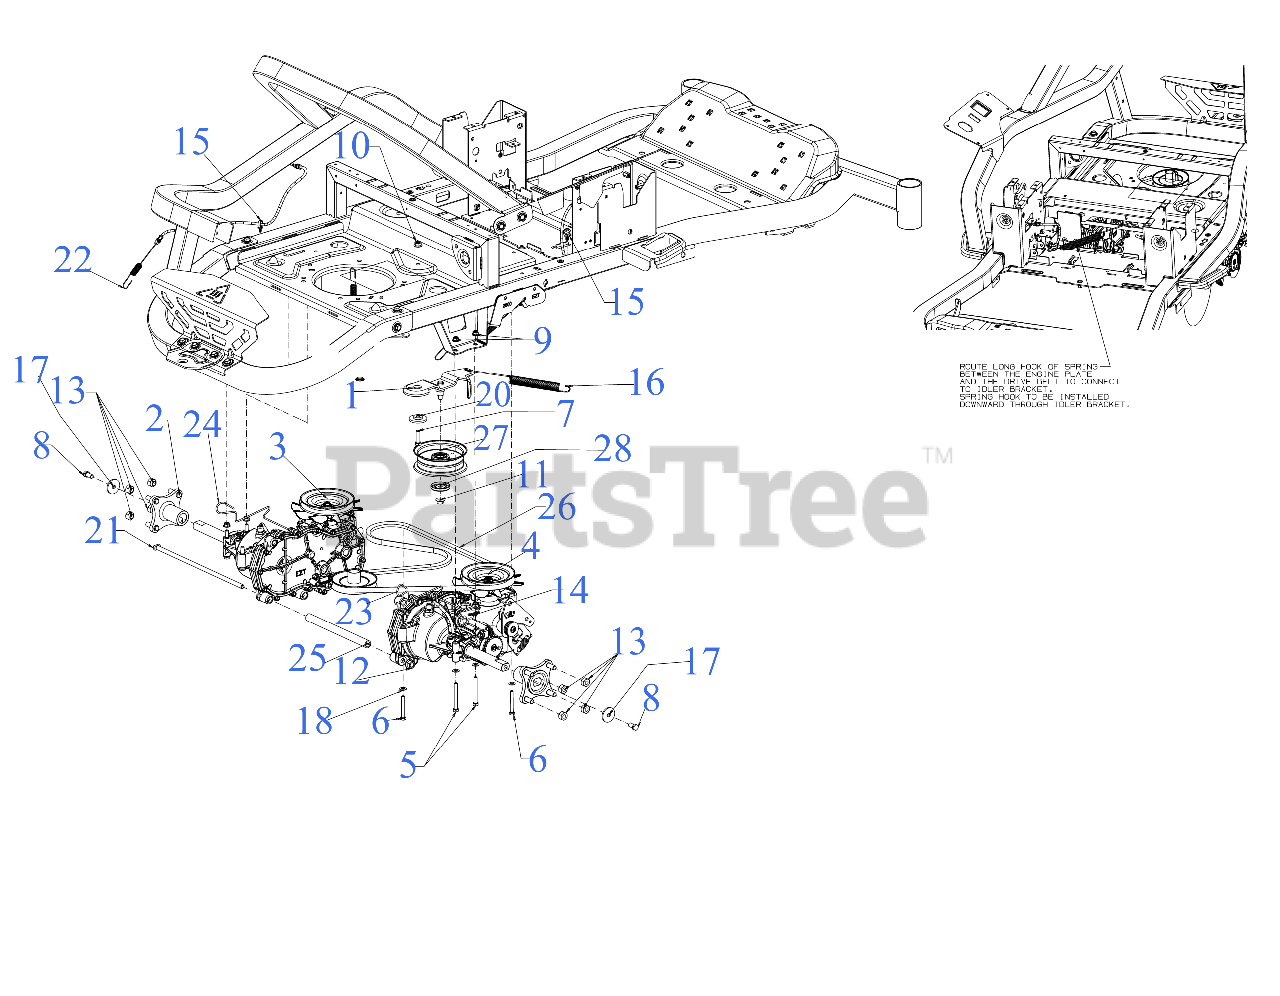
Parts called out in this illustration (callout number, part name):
1	DRIVE IDLER BRACKET ASSEMBLY
2	WHEEL HUB ASSEMBLY
2	STUD 7/16-14 x 1.6
3	HYDRO TRANSMISSION (LH)
4	HYDRO TRANSMISSION (RH)
5	HEX SCREW 5/16-18 x 2.75
6	HEX SCREW 5/16-18 x 2.25 GR5
7	SCREW 3/8-16 x 1.25 GR5
8	SCREW 3/8-16 x .75 GR 5
9	FLANGE LOCK NUT 5/16-18
11	FLANGE LOCK NUT
12	FLANGE LOCK NUT
13	LUG NUT 7/16-14
14	BOW TIE COTTER PIN 1/4-5/16
15	CABLE RETAINER CLIP
16	EXTENSION SPRING .75 DIA X 10.27
17	FLAT WASHER
18	FLAT WASHER
20	SHOULDER SPACER
21	SUPPORT TUBE ROD
22	PARK BRAKE CABLE
23	HYDRO BYPASS ROD (RH)
24	HYDRO BYPASS ROD (LH)
25	SUPPORT TUBE
26	BELT-TRANS DRIVE A x 69.1
26	Cub Cadet DRIVE BELT (-05874)
27	IDLER PULLEY 4.50" DIA
28	IDLER PULLEY CAP
